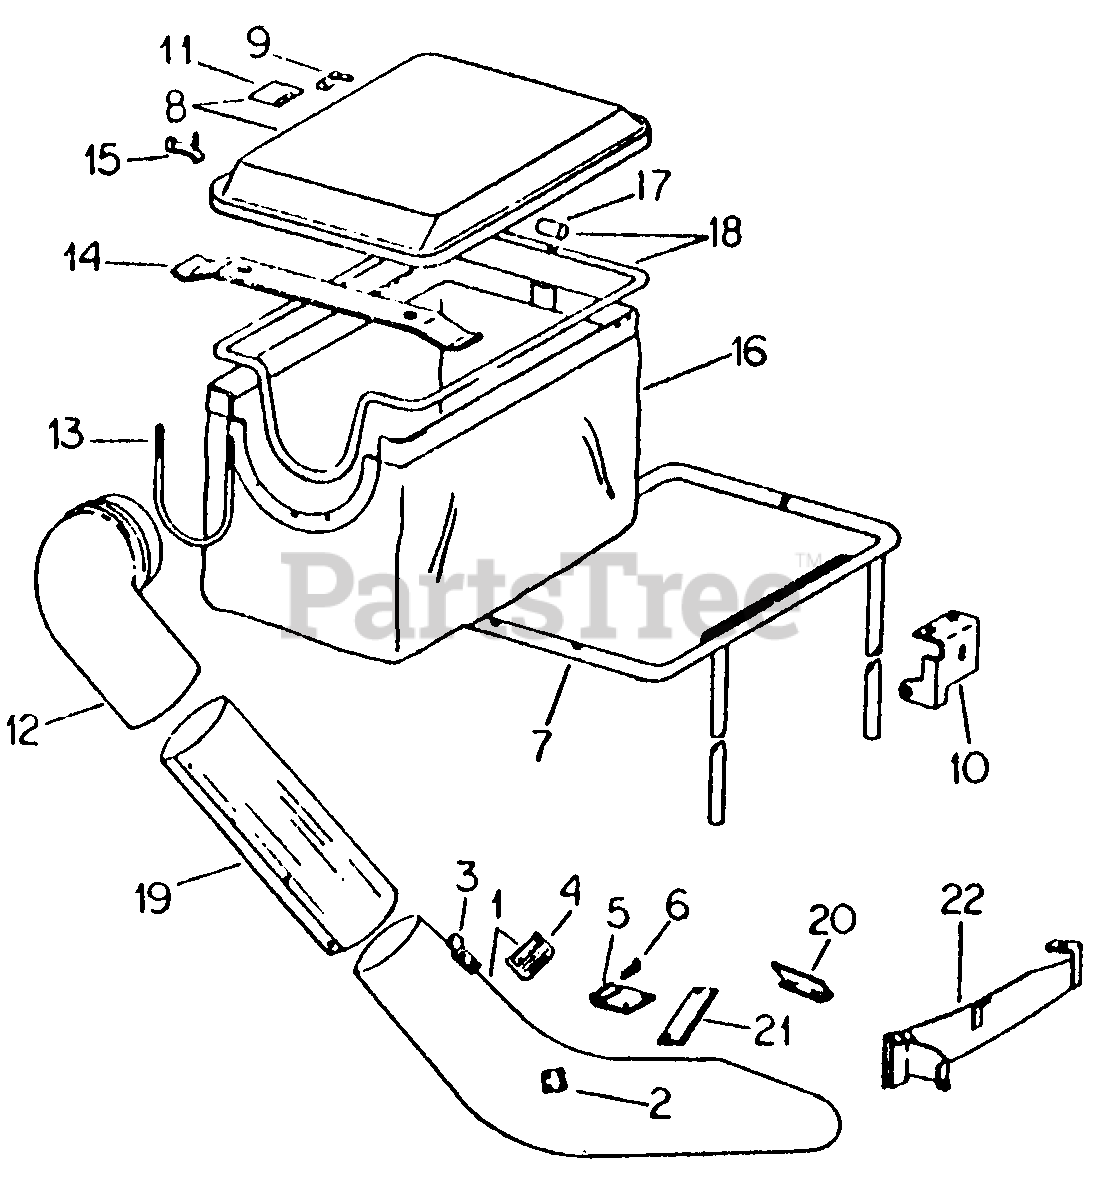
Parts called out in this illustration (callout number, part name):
1	CHUTE ASSY, DISCHARGE
2	HINGE, CHUTE
3	RETAINER, TUBE
4	PRODUCT GRAPHIC, CAUTION
5	SCREW, 1/4 X 1/2 ZNP P/HSD MACH
6	PIN, INTERNAL COT.
7	FRAME ASSY, BAGGER
8	COVER ASSY, GRASS BAG
9	CLIP, COVER
10	SUPPORT, COVER FURNISHED AS PART OF 703-0637
11	PRODUCT GRAPHIC, CAUTION-MOWER INSTRTNS FURNISHED AS PART OF 703-0637
12	ELBOW, CHUTE
13	BRACKET, ELBOW
14	SPRING, BAG RETAINER
15	CATCH ASSY
16	BAG ASSY, GRASS
19	SHEET, CONNECTING TUBE
20	IMPELLER, 36 IN. MOWER BLADE
21	FLANGE, LOCATOR
